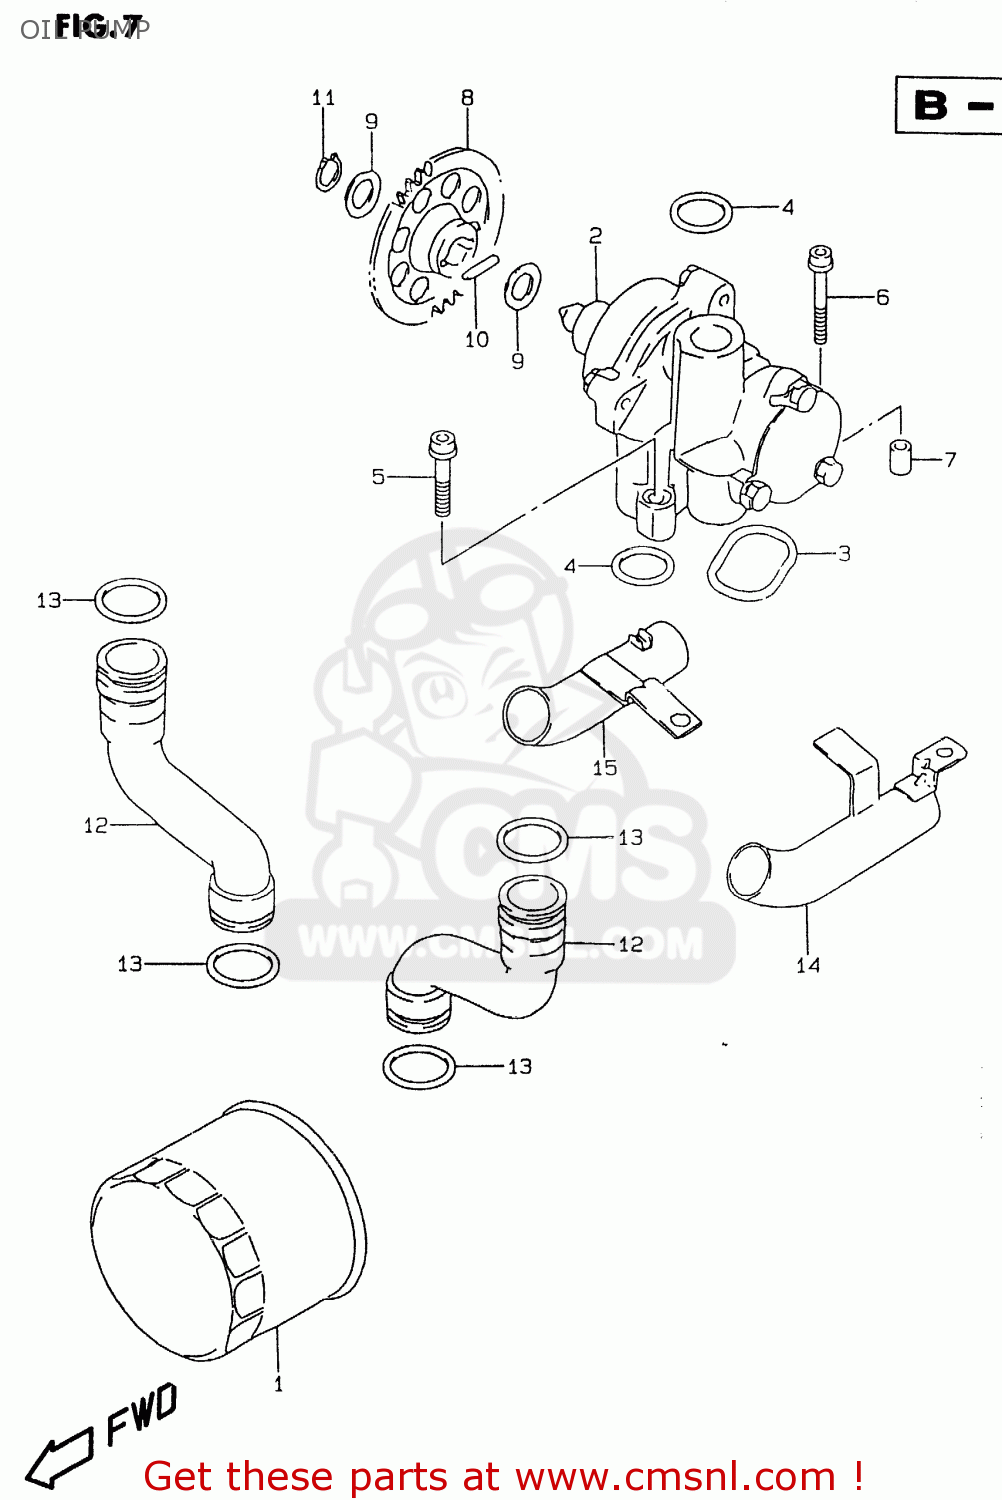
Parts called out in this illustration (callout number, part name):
1	FILTER ASSEMBLY,ENGINE OIL
2	PUMP ASSY,OIL
3	O RING,OIL PUMP
4	O RING(D:3.2,ID:17.8)
5	BOLT
6	BOLT
7	PIN
8	GEAR,OIL PUMP DRIVEN(NT:37)
9	SHIM
10	PIN(5X18)
11	CIRCLIP,12 MM
12	PIPE,OIL OUTLET
13	O RING(D:3.7,ID:21.7)
14	PIPE,OIL OUTLET UNDER,L
15	PIPE,OIL OUTLET UNDER,R
